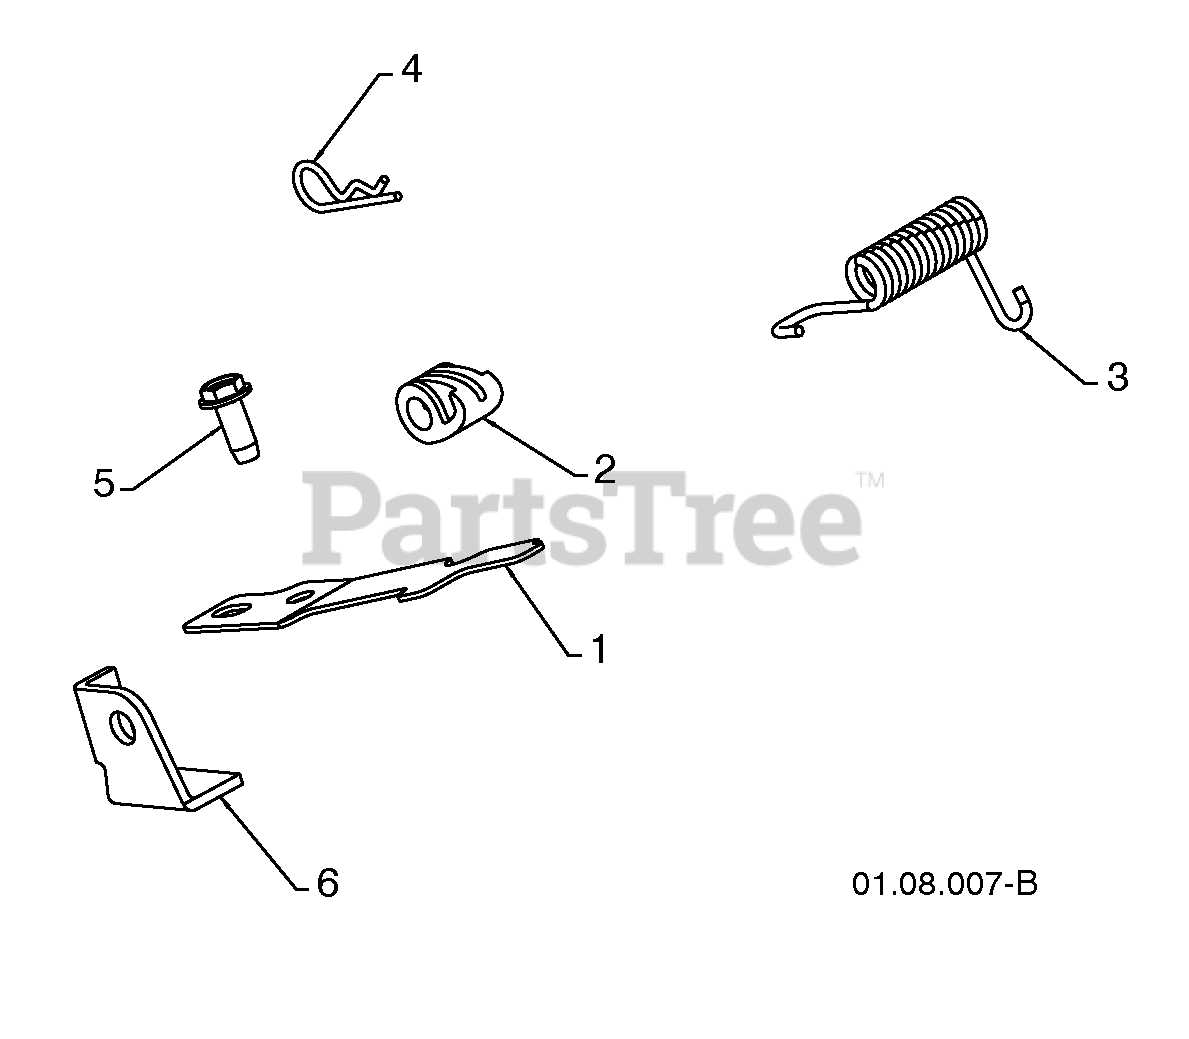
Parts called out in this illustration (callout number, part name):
1	RP SPRING.INTERLOCK
2	CAM.INTERLOCK.RELEASE
3	RP SPRING, TORSION
4	SPRING RETAINER
5	SCREW 14-20 X 5/8
6	STOP.INTERTLOCK.SPRING.
